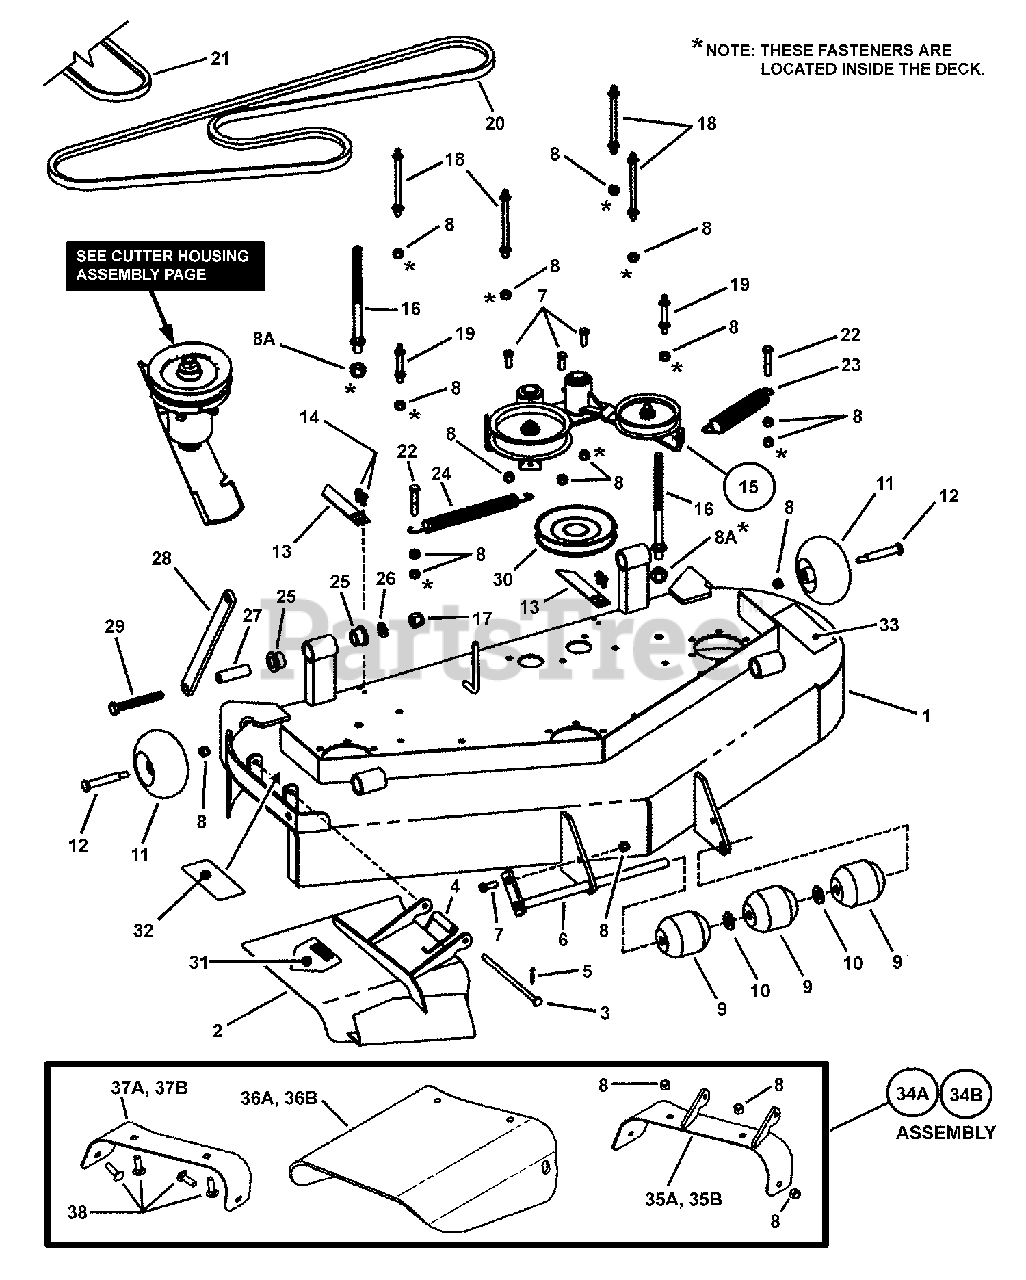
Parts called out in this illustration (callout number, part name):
1	WELDMENT, 48" Deck
1	WELDMENT, 52" Deck
1	WELDMENT, 61" Deck
2	DEFLECTOR, 48" Deck ANSI Compliant (Weldment)
2	DEFLECTOR, 52" Deck Euro (Weldment)
2	DEFLECTOR, 61" Deck Euro (Weldment)
3	HINGE PIN, Chute
4	SPRING, Chute
5	COTTER PIN, 3/32 x 1"
6	PIVOT, Roller Pin (Weldment)
7	BOLT, 3/8-16 X 1" GD5 CZ
8	NUT, 3/8-16 HEX NYLON LOCK
8A	NUT, 1/2-13 HEX SIDE LOCK
9	ROLLER, Low Density Polyethylene
10	WASHER, 5/8" Flat
11	WHEEL, Gage
12	BOLT, 1/2" Dia. Shoulder, 3/8-16 Thread
13	POINTER, Height-of-Cut
14	SCREW, 1/4-20 x 5/8" Hex Washer Self-Tap
15	ASSEMBLY, Idler - 3 Spindle Deck
16	STUD, Lift, 1/2-13 Thread, Both Ends
17	NUT, 1/2-13 Hex Nyloc
18	STANDOFF, 4-1/2" Long (5/16-18 thread top; 3/8-16 bottom)
19	STANDOFF, 2" Long (5/16-18 thread top ; 3/8-16 bottom)
20	* V-BELT, Secondary, 48" Deck (113" Nom. Eff. Length)
20	* V-BELT, Secondary, 52" Deck (120" Nom. Eff. Length)
20	* V-BELT, Secondary, 61" Deck (128" Nom. Eff. Length)
21	* V-BELT, Primary, 48" Deck (66" Nom. Eff. Length)
21	* V-BELT, Primary, 52" Deck (69" Nom. Eff. Length)
21	* V-BELT, Primary, 61" Deck (72" Nom. Eff. Length)
22	BOLT, 3/8-16 X 2, GD5, CZ
23	SPRING, Idler
24	SPRING, Extension, Primary Idler
25	BUSHING, Suspension
26	WASHER, 1/2" Flat
27	SLEEVE, Suspension
28	ARM, Suspension, 12" Long
28	ARM, Suspension, 13-1/2" Long
29	BOLT, 1/2-13 x 3-3/4" Hex Head, GR 5
30	PULLEY, 5-3/4" O.D. w/Hub
30	PULLEY, 6-5/8" Driven
31	DECAL, Warning (CPSC Cut Finger)
32	DECAL, Danger Guard/Catcher
33	DECAL, Caution- Operator Instruction
34A	ASSEMBLY, 48" Discharge Chute
34B	ASSEMBLY, 52" Discharge Chute
35A	WELDMENT, 48" Deflector Top
35B	WELDMENT, 52" Deflector Top
36A	CHUTE, Rubber (48")
36B	CHUTE, Rubber (52")
37A	DEFLECTOR, Bottom (48")
37B	DEFLECTOR, Bottom (52")
38	BOLT, 3/8-16 x 1-1/4" Square Neck Carriage, GR 5
